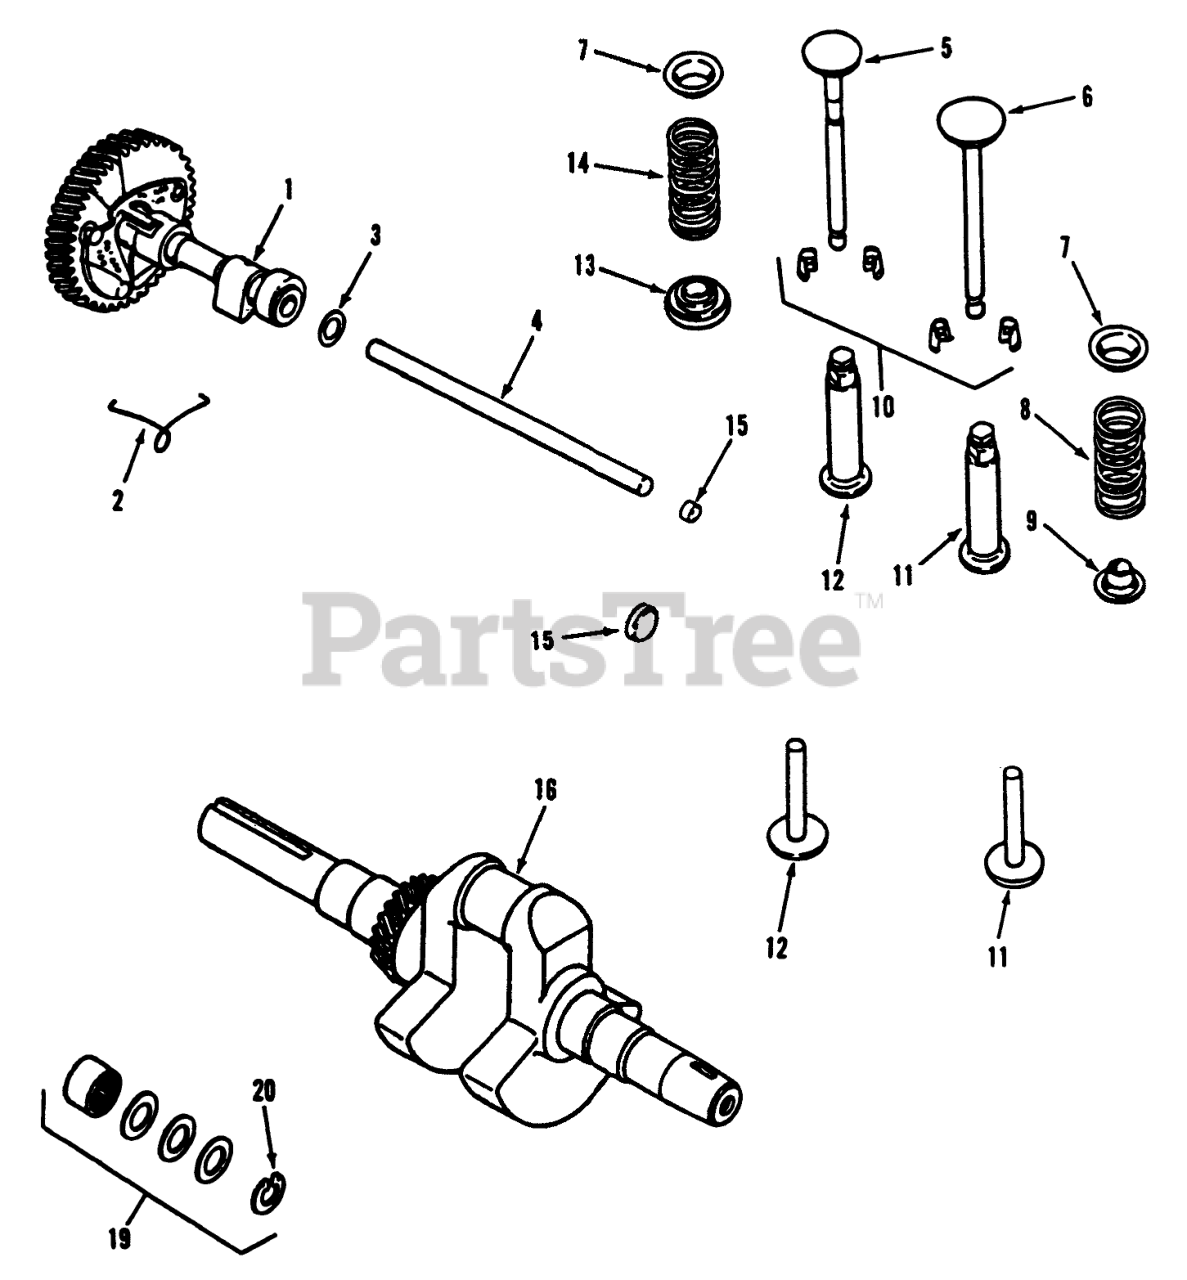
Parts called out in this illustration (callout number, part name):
1	Camshaft Assy (Includes Item 2)
2	Spring
3	Spacer .005
4	Camshaft Pin
5	Valve-Exhaust
6	Valve-Intake
7	UpperSpring Retainer
8	Spring
9	Retainer-Spring
10	Kit-Retainer
11	Tappet
12	Tappet
13	Rotator-Valve
14	Spring
16	Kit-Crankshaft 3-25/32 x 1-1/8 (Includes Flywheel Hdwr.)
19	Kit-Spacer (Includes Item 20)
20	Retainer
